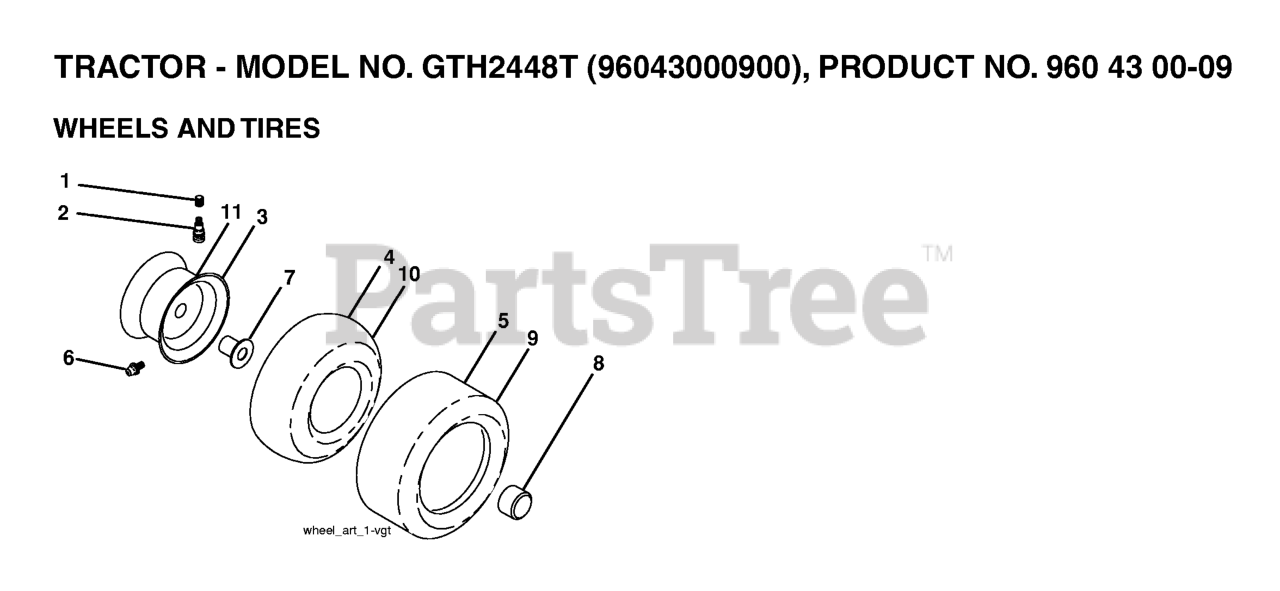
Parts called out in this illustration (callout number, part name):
2	VALVE STEM LT
3	RIM ASSEMBLY, FRONT
4	TUBE.5.3/4.5/6
5	TIRE HEAVY DUTY
6	FITTING LT
7	BEARING T
8	CAP, AXLE BLK
9	TIRE.22X9.50-12.TURF.SAVER.REA
10	TUBE
11	RIM.ASM.12".REAR.SILVER
